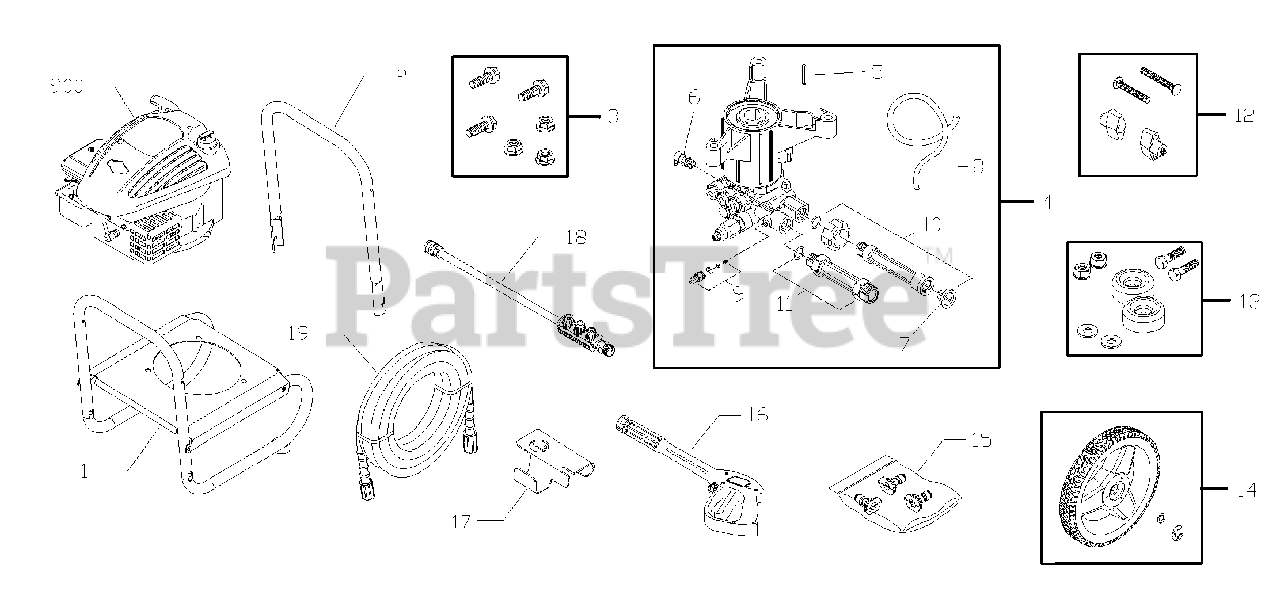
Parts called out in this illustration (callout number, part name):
2	HANDLE
3	KIT, Hardware, Engine Mounting
4	PUMP
6	VALVE, Thermo Relief
7	FILTER, Garden Hose
8	HOSE, Chemical
9	KIT, Chemical Injection
10	KIT, Water Inlet
12	KIT, Hardware, Handle
13	MOUNT, Vibration
15	KIT, QC Nozzles
16	GUN
19	HOSE
900	* ENGINE
